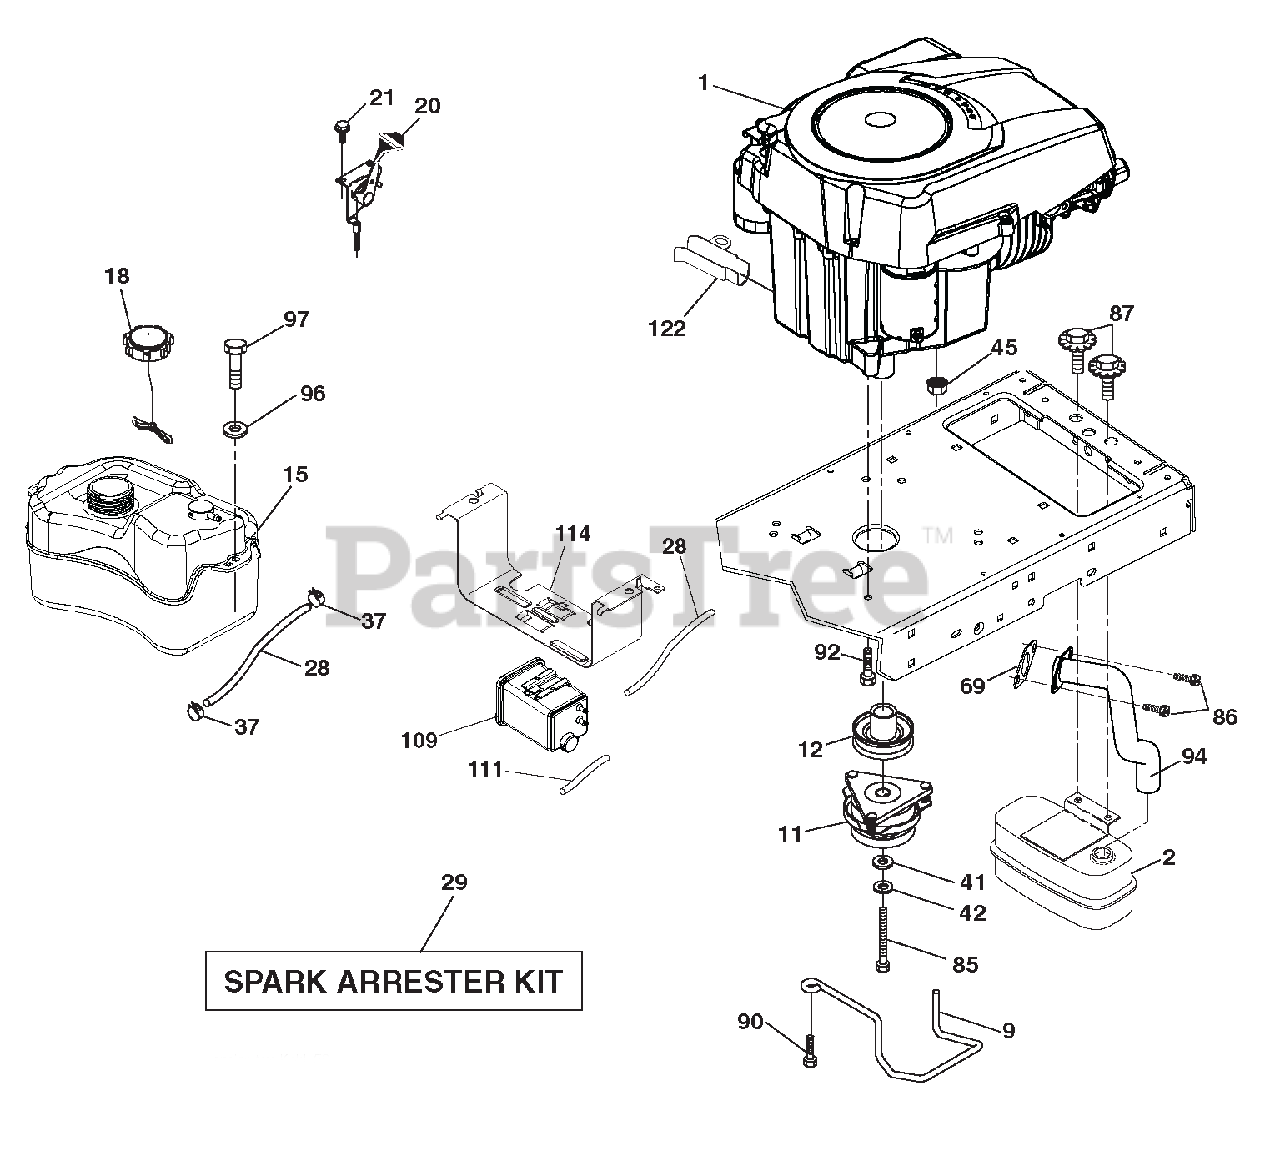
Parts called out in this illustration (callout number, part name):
1	ENGINE KOHL MODEL NO. SV530-3225 (581497301) (ORDER PARTS FROM ENGINE MANUFACTURER.)
2	MUFFLER
9	KEEPER.BELT.ENGINE.3.25"NSTL
11	CLUTCH OGURA
12	PULLEY. ENGINE. 1" CRK.
15	TANK FUEL
18	CAP FUEL
20	CONTROL THROTTLE/CHOKE
28	LINE.FUEL.22"FRONT.EMIS.CA.LP
29	KIT.SPARK ARRESTOR(392390 B&S)
37	CLAMP.HOSE.BLK.
41	WASHER.1-1/2 ODX15/32 IDX.250
42	WASHER.LOCK.HVY HLCL.SPR.7/16
45	Nut, Keps Hex 1/4-20 unc
69	GASKET.KOHLER.SV.I.
85	BOLT.HEX.7/16-20X4XGR5-1.5THR.
86	SCREW SOCKET HEAD 5/16-18 X 1
87	BOLT.5/16-18UNCX3/4 W/SEMS.BLK
90	SCREW.3/8-16X1.SMGML.TAP/R.BLK
92	SCREW.3/8-16 X 1.SMGML.TAP/R
94	TUBE.EXHAUST.KOHL.COURAGE
96	WASHER.9/32 X 7/8 X 16GA.
97	SCREW.HEXWSH.THDROL.1/4-20X3/4
109	CANISTER.CARBON.FILTER ASM.TEX
111	PURGE.LINE.CARB
114	CRADLE.CANISTER.CARBON
122	Extension Drain Oil
